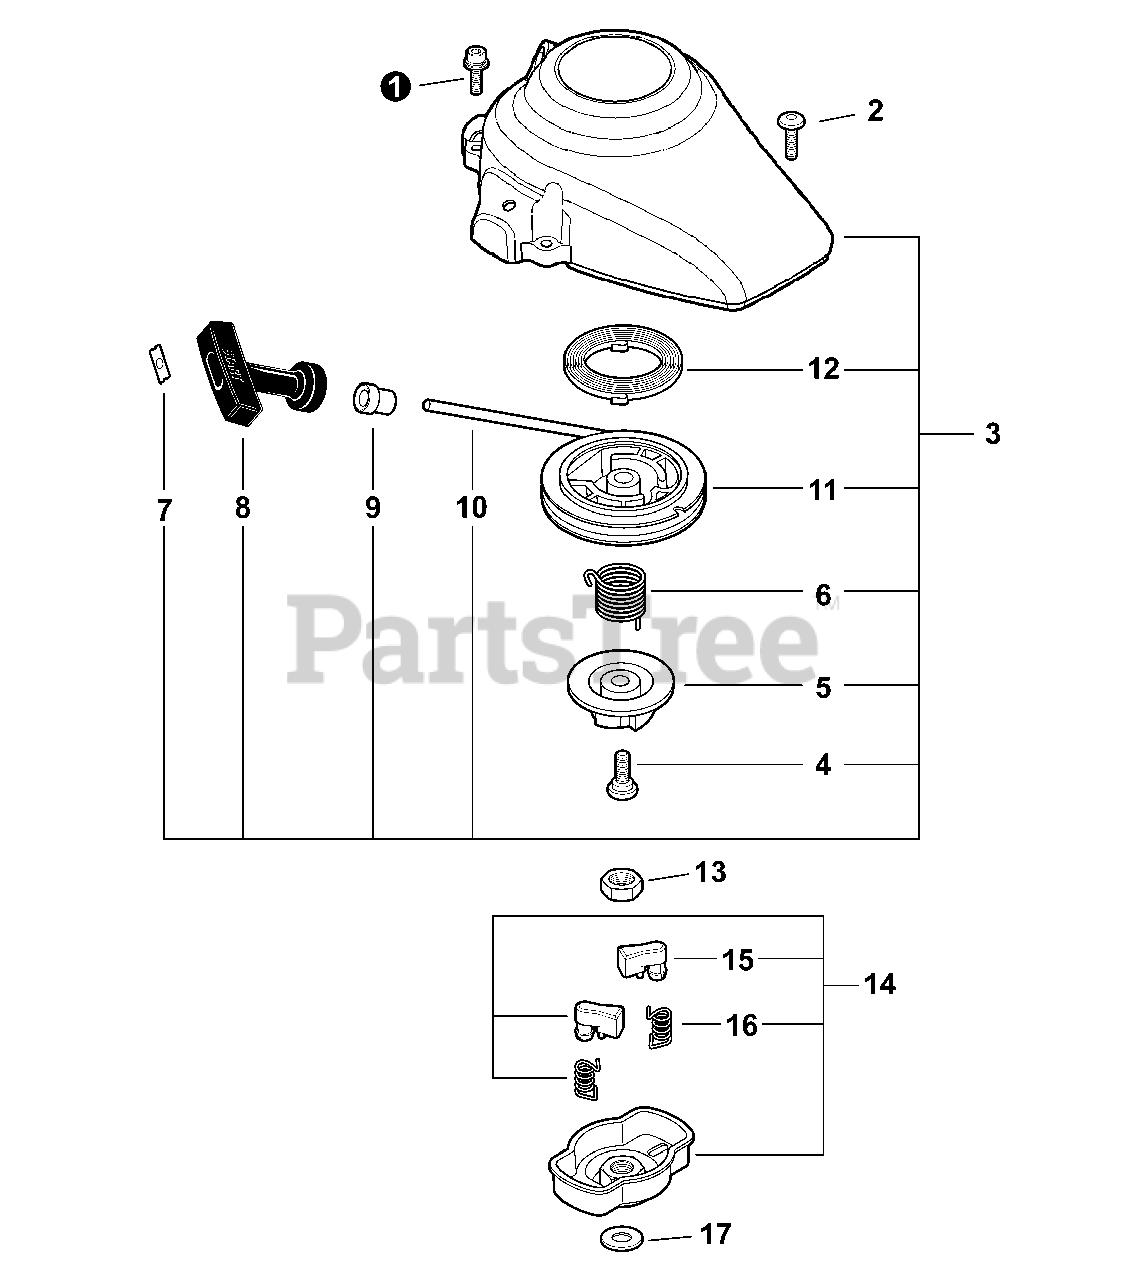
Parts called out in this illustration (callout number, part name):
1	BOLT 4×16
2	BOLT 4×12
3	STARTER ASSY, RECOIL
4	SCREW
5	PAWL CATCHER
6	SPRING, TORSION
7	RETAINER, ROPE
8	GRIP, STARTER
9	GUIDE, ROPE
10	ROPE, STARTER 3×700
11	REEL, ROPE
12	SPRING, RECOIL
14	PULLEY ASSY, STARTER
15	PAWL, STARTER
16	SPRING, RETURN
17	WASHER 8.5×16×1.2
